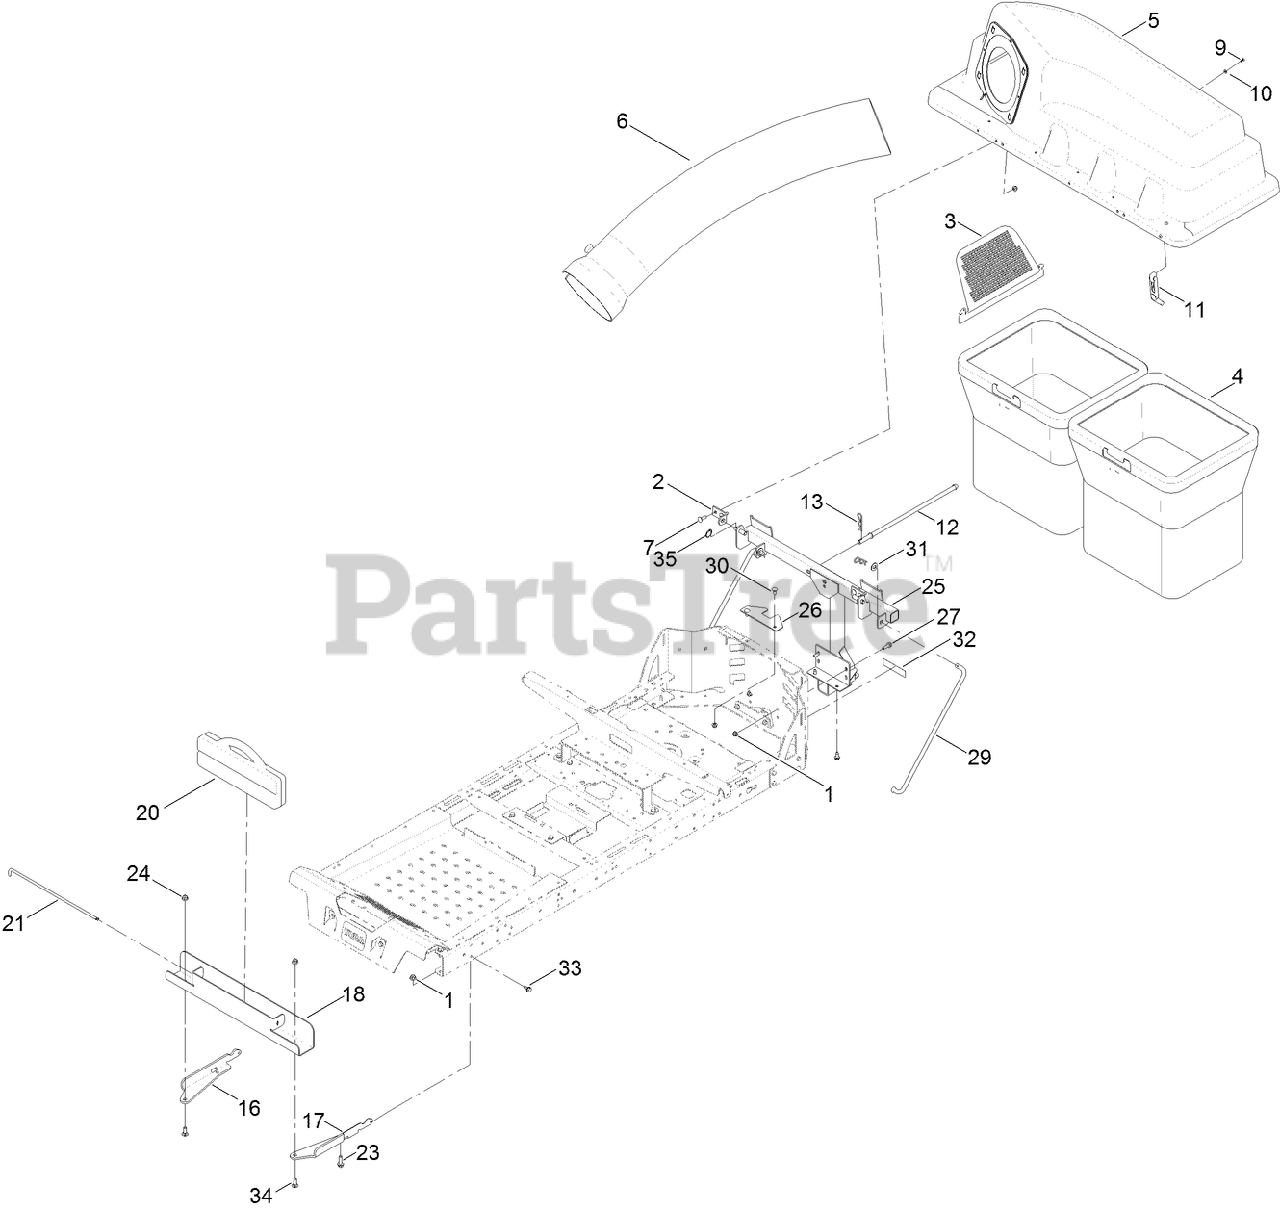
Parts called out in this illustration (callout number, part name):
1	NUT-HF, NI
2	BRACKET-PIVOT, HOPPER
3	SCREEN-BAGGER
4	BAG ASM
5	BAGGER TOP ASM
6	TUBE-BAGGER
7	BOLT-CARR
9	SCREW-PLASTIC, PTH
10	WASHER-FLAT
11	LATCH-RUBBER
12	ROD-HOOD, DOWN (HOLD)
13	PIN-HAIR
16	BRACKET-WEIGHT, RH
17	BRACKET-WEIGHT, LH
18	CHANNEL-WEIGHT, BAGGER
20	WEIGHT-35 POUND
21	PIN-WEIGHT
23	SCREW-HHF
24	NUT-HF, NI
25	FRAME-PIVOT
26	BRACKET-STABILIZER
27	SCREW-HHF
29	ROD-SUPPORT
30	BOLT-CARR
31	WASHER-FLAT
33	SCREW-HWHTF
34	BOLT-CARR
35	PIN-COTTER, CIRCULAR
